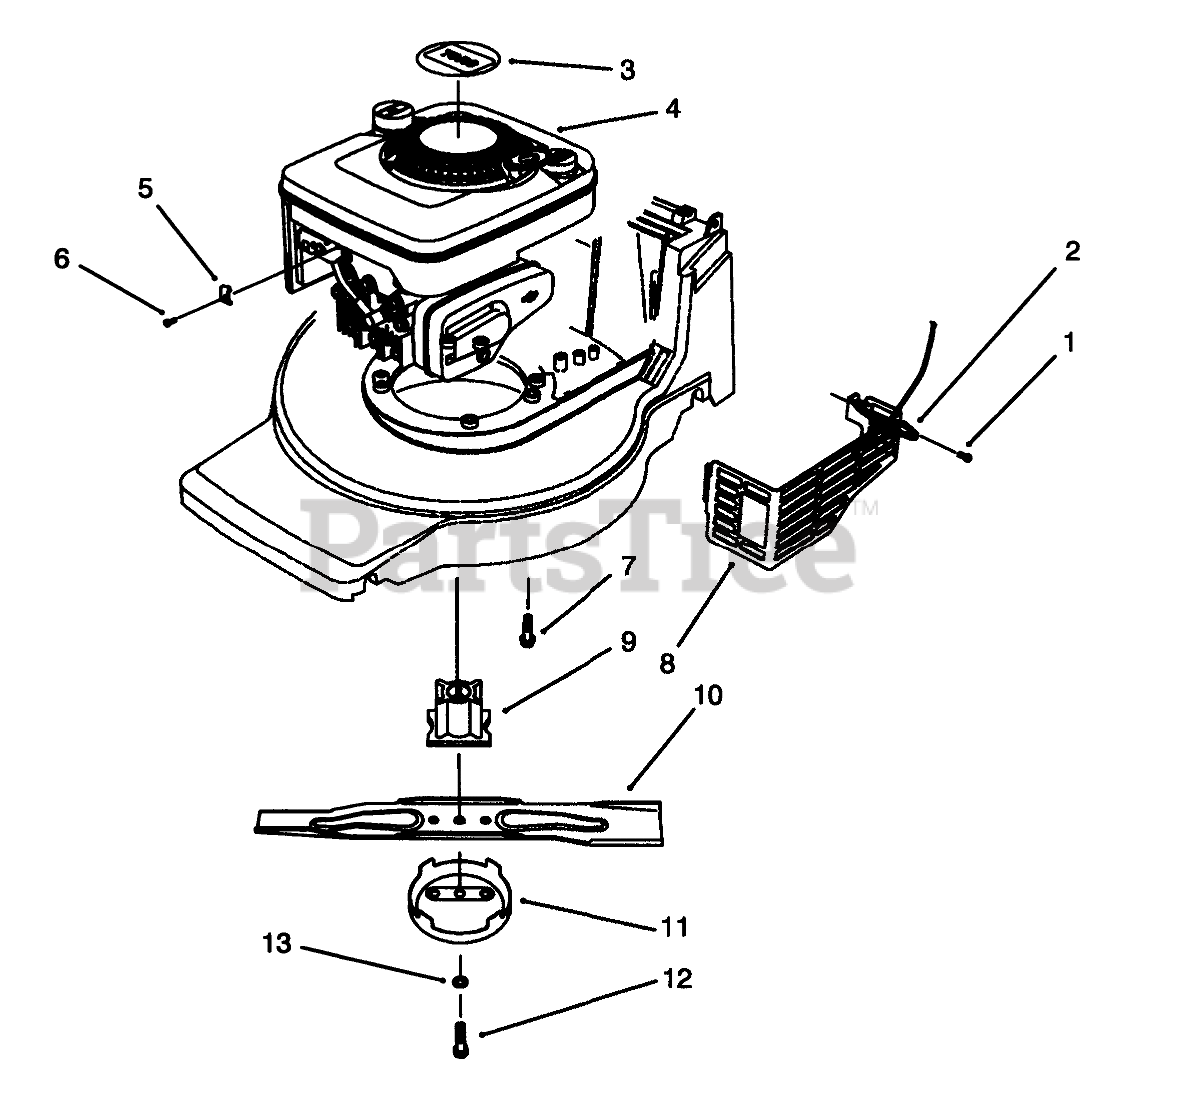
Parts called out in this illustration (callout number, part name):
1	SCREW-HWH
2	TIE-CABLE
3	DECAL - RECOIL
4	Engine-B & S Quantum
5	CLAMP-CASING
6	CLAMP SCREW F/W ENGINE
7	SCREW-HWH
8	SHIELD-MUFFLER
9	BLADE RETAINER - 25 MM
10	Blade-48cm
11	CUP-SCALP, ANTI
12	BOLT-BLADE
13	WASHER-LOCK
